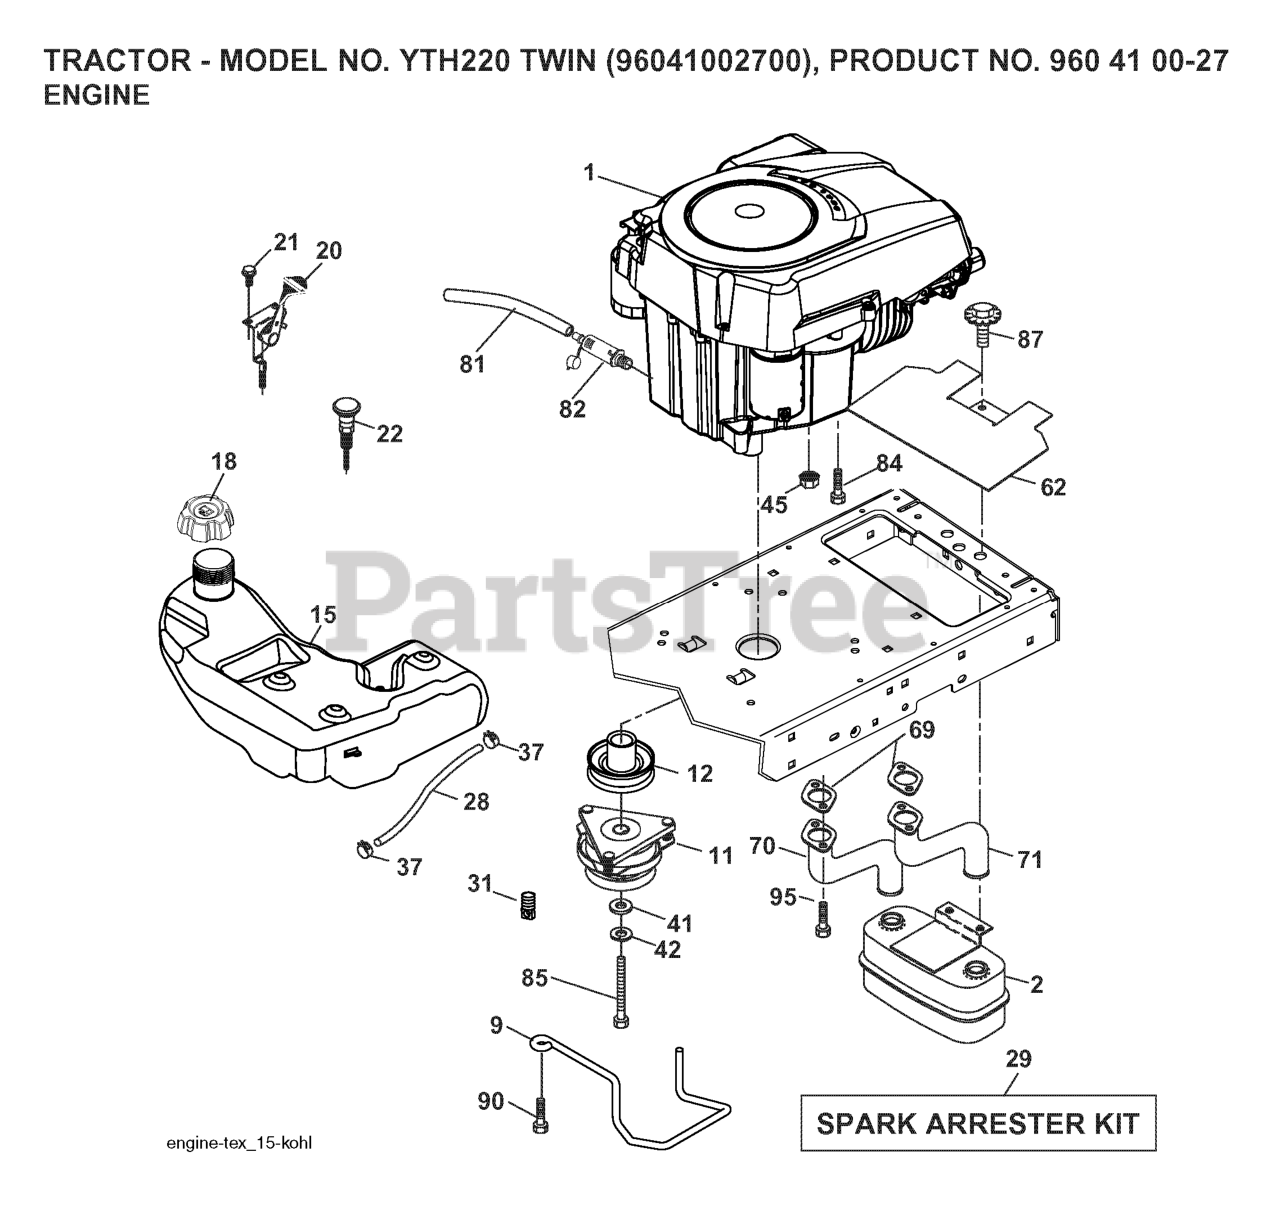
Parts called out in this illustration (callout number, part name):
2	MUFFLER.TWIN.CYL.LOW.TONE
9	KEEPER.BELT.ENGINE.3.25 (3 2)
11	CLUTCH MZ ZTR GT.48/54"1.125"
12	PULLEY.ASM.ENGINE.1-1/8X3-1/4
15	TANK.FUEL.4GAL
18	CAP.FUEL.TANK.3"GREY
20	THROTTLE CONTROL
21	SCREW
22	CONTROL.CHOKE.ERGO.PUSH-IN.BLA
28	REPL BY 532 00 85-43
29	KIT.SPARK ARRESTOR 794945 B&S
37	HOSE CLAMP
42	LOCKWASHER
45	NUT
62	RP SHIELD HEAT MUFFLER
70	RP.PIPE-EXHAUST LH
71	RP.PIPE-EXHAUST RH
81	TUBE, DRAIN OIL ASM.
82	PLUG DRAIN OIL EASY
84	SCREW.3/8-16
85	BOLT HEX 7/16-20 X 3.75 GR. 5
87	BOLT.5/16-18UNCX1.W/SEMS.BLK
90	SCREW 3/8-16X1
95	SCREW.SOCKET HD.5/16-1
